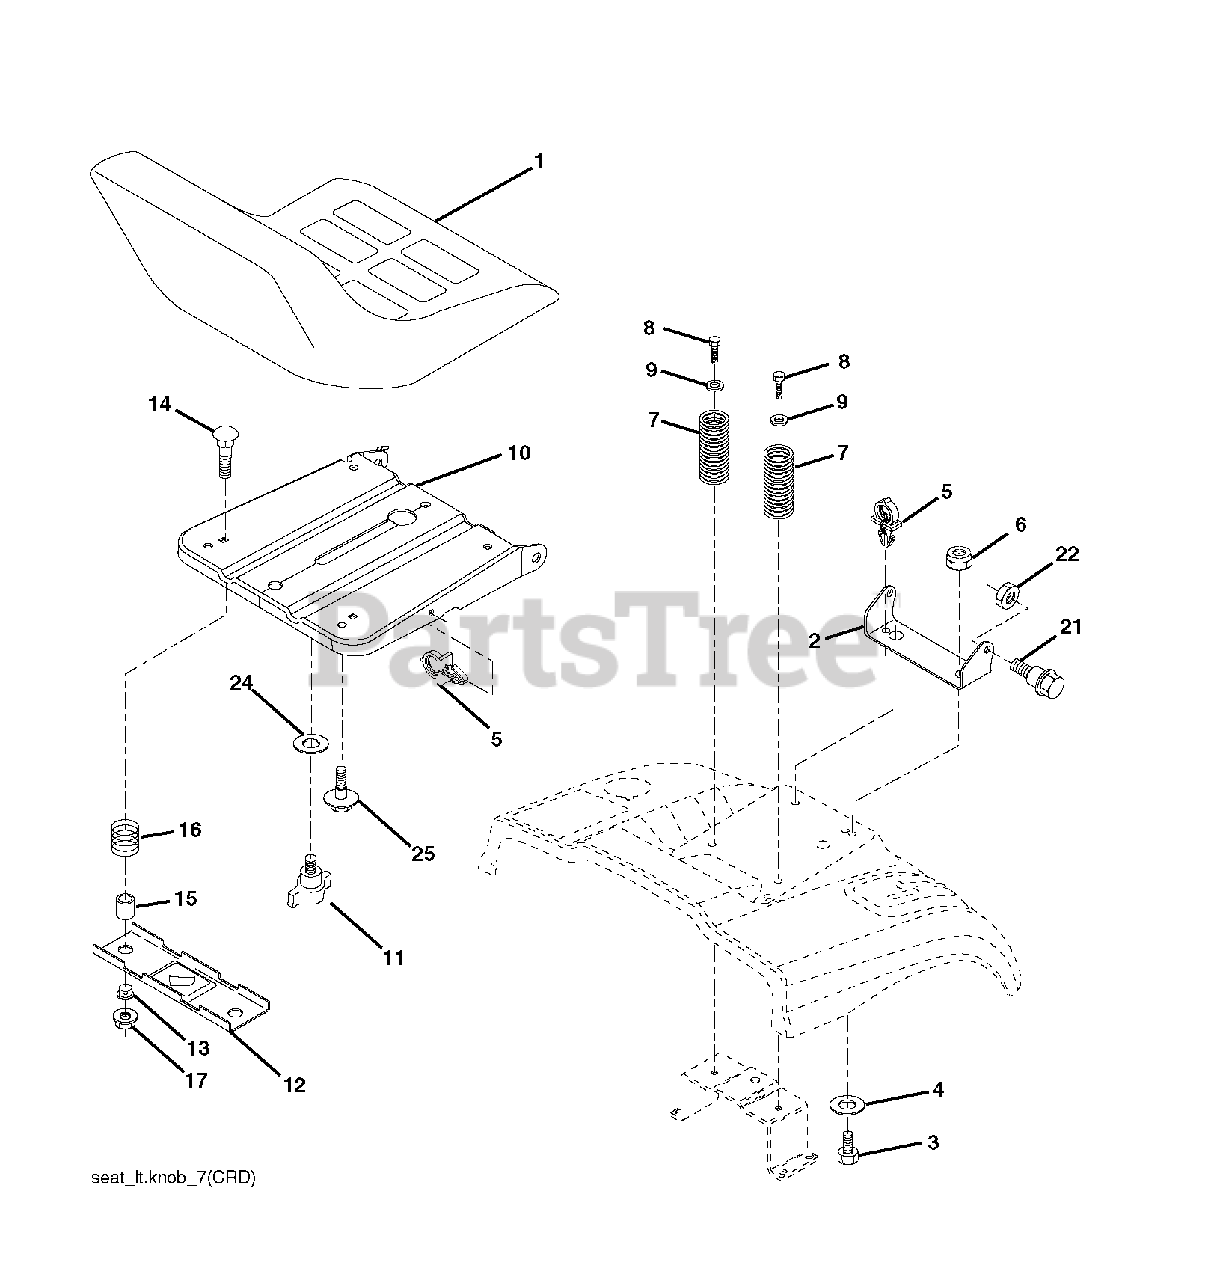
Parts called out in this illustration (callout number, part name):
2	SEAT PIVOT BRKT
4	WASHER PM
5	PUSH CLIP
6	NUT
7	SPRING COMPRESSION
8	SCREW 3/8-16X1
9	WASHER
10	PAN.ASM.SEAT.1SLOT
11	KNOB.SEAT.ADJ.WINGNUT
12	BRKT.MNTNG.SWITCH.SEAT
14	BOLT.ROUND.HEAD.SQUARE.NECK
15	SPACER SPLIT 28X.96
17	NUT T
21	BOLT.SHOULDER.5/16-18
22	NUT.71038.31-18.HEX.NYLOCK
25	BOLT,SHOULD
